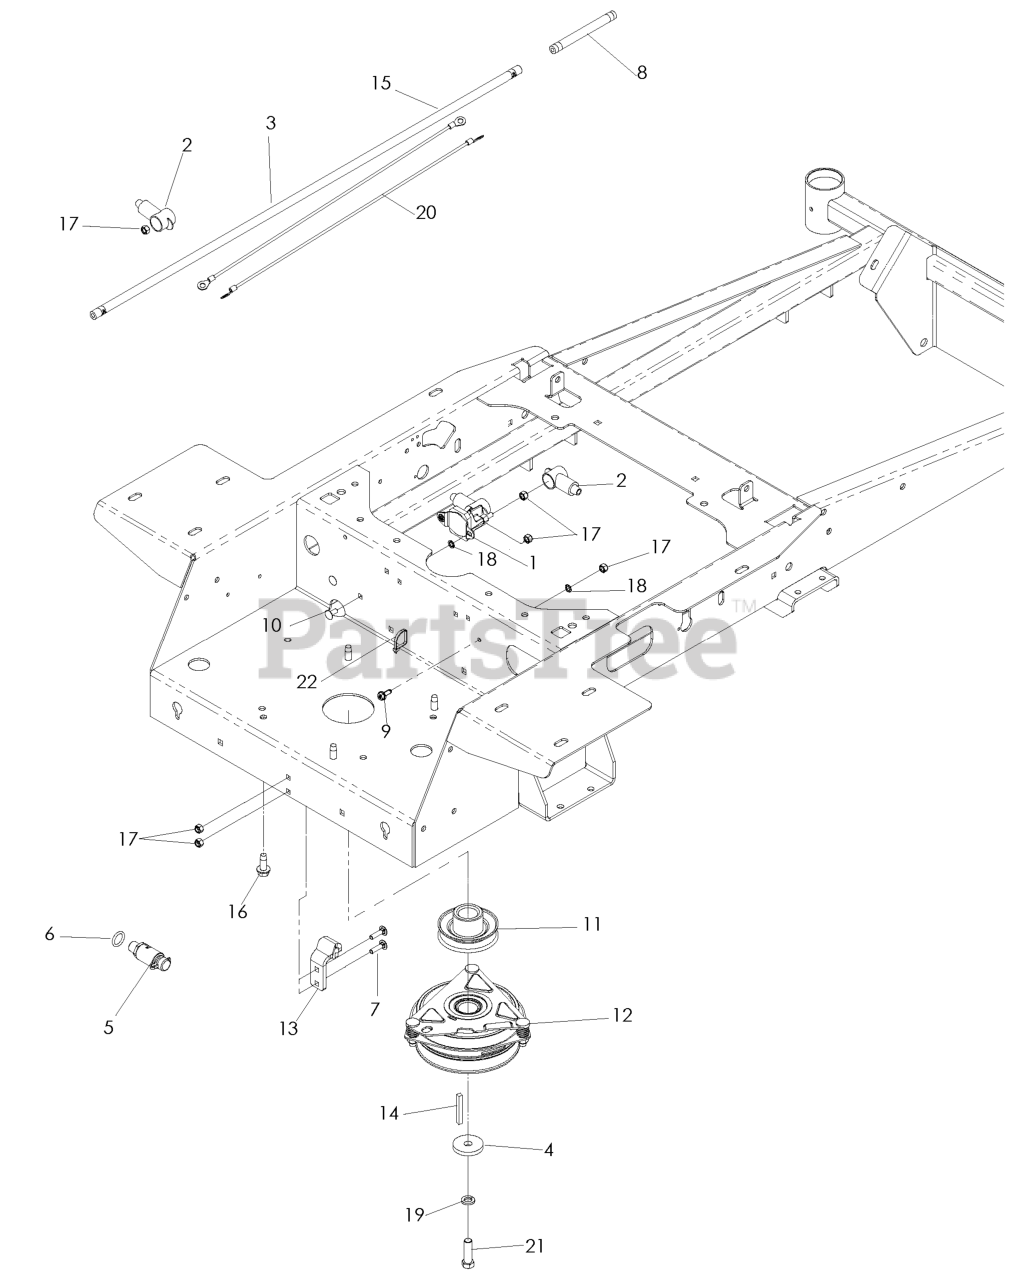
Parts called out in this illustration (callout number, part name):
4	SPINDLE WASHER
5	OIL DRAIN FITTING
6	WASHER 5/16 EXT STAR
7	RHSNB, 1/4-20 X 1, GR5
8	FUEL LINE 5"
9	SCREW- 1/4-20 X 5/8
10	RHSSNB, 1/4-20X5/8
11	PULLEY, DRIVE
12	CLUTCH, 150 FT/LBS
13	TIE DOWN, CLUTCH
14	KEY 1/4 SQ X 2
15	HOSE CLAMP
16	BOLT 3/8-16 X 1.0
17	NUT.1/4-20.HEX.NYLOC.ZD
18	WASHER 1/4 INT TOOTH
19	WASHER 7/16 LOCK
20	CABLE POSITIVE, LONG
21	HCS 7/16F X 1 1/2
22	TIE, PLASTIC
